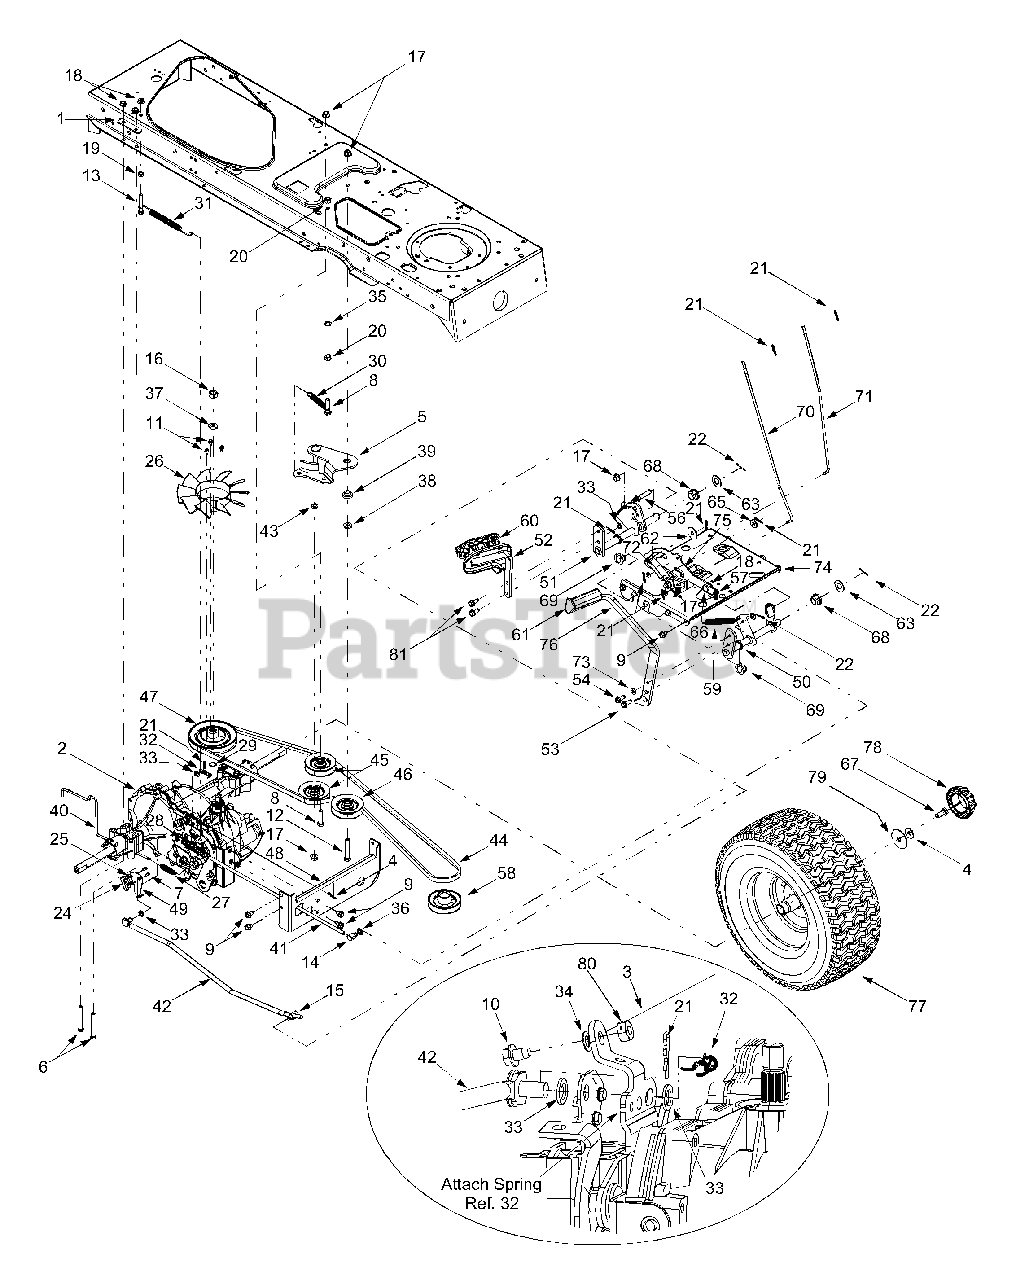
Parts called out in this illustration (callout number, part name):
2	Hydrostatic Transmission
3	Reverse Wire Harness Adapter & Ground
4	Bell Washer,.34 x.872
5	Double Idler Bracket Assembly
6	Hex Cap Screw, 5/16-18 x 2.75
7	Screw, #8-18 x.5
8	Hex Cap Screw, 3/8-16 x 1.5
9	Self-tapping Screw, 5/16-18 x.625
10	Self-tapping Screw, 1/4-20 x.375
11	Screw, #12-24 x.375
12	Hex Cap Screw, 3/8-16 x 2.25
13	Hex Cap Screw, 5/16-18 x 2.0
14	Ferrule, 5/16-18
15	Ferrule, 3/8-24
16	Hex Nut, 1/2-20
17	Flange Lock Nut, 3/8-16
18	Flange Lock Nut, 5/16-18
19	Hex Nut, 5/16-18
20	Hex Nut, 3/8-16
21	Internal Cotter Pin
22	Cotter Pin
24	Short Spring Switch
25	Insulator Nut Plate
26	10-inch Fan
27	Extension Spring,.48 x 2.03
28	Extension Spring,.59 x 4.0
29	Wire Ring
30	Extension Spring,.5 x 3.97
31	Extension Spring,.5 x 7.0
32	Extension Spring, 3/8 x 1.44
33	Flat Washer,.385 x.62 x.063
34	Flat Washer,.281 x.50 x.063
35	Lock Washer, 3/8
36	Flat Washer,.344 x.688 x.065
37	Lock Washer, 1/2
38	Flat Washer,.407 x.812 x.135
39	Shoulder Spacer,.38
40	Hydrostatic Bypass Rod
41	Hydrostatic Brake Rod
42	Hydrostatic Control Rod
43	Spacer,.376 x.625 x.22
44	Drive Belt
45	V-idler Pulley, 3.06
46	Flat Idler Pulley, 2.75
47	Input Pulley, 5.0
52	Hydro Pedal Assembly
53	Self-tapping Screw, 5/16-18 x.875
54	Self-tapping Screw, 5/16-18 x.75
56	Pin, 3/8-16 x 2.43
57	Compression Spring,.405 OD x 1.17
58	Engine Pulley
59	Extension Spring,.50 OD x 6.37
60	Drive Pedal Pad
61	Brake Pedal Pad
62	Flat Washer,.411 x 1.25 x 1.0
63	Flat Washer,.64 x 1.24 x.06
65	Flat Washer,.406 x.875 x.105
66	Shoulder Screw,.437 x 1.62
67	Hex Cap Screw, 5/16-24 x.75
68	Hex Flange Bearing
69	Split Hex Flange Bearing
70	Cruise Control Rod
71	Brake Lock Control Rod
72	Cruise Latch
73	Flat Washer,.344 x.750 x.120
75	Drive Lockout Bracket
78	Deluxe Hub Cap (Ref. 79 Required)
79	Flat Washer,.350 x 1.59 x.062
80	Hex Lock Nut, 1/4-20
81	Screw, 5/16-18 x.750
